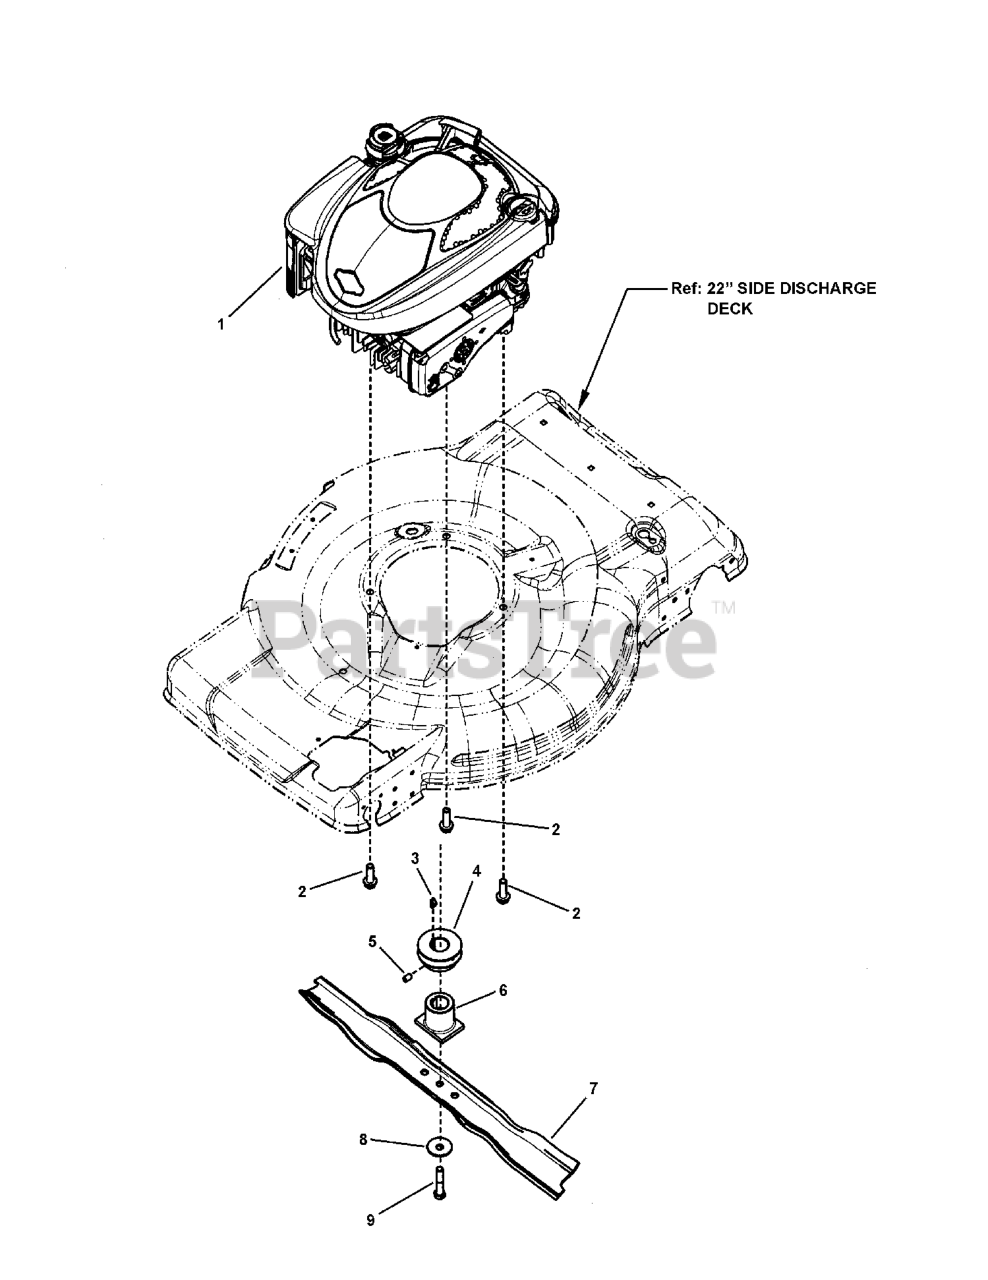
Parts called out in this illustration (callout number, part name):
1	* ENGINE, B&S 675 Series, X-Spec, F3, MY09
2	SCREW, 3/8-16 x 1-1/4" Hex Washer Self-Tap
3	KEY, #HP-506 Hi-Pro
4	PULLEY, Engine
5	SET SCREW, 5/16-18 x 1/2" Hex Recess
6	BLADE HUB, 21" WBM, Rear Discharge, 2 Position
7	BLADE, Wave, Steel Deck
8	WASHER, Cone
9	SCREW, 3/8-24 x 2" Hex Head Cap, GR 5
